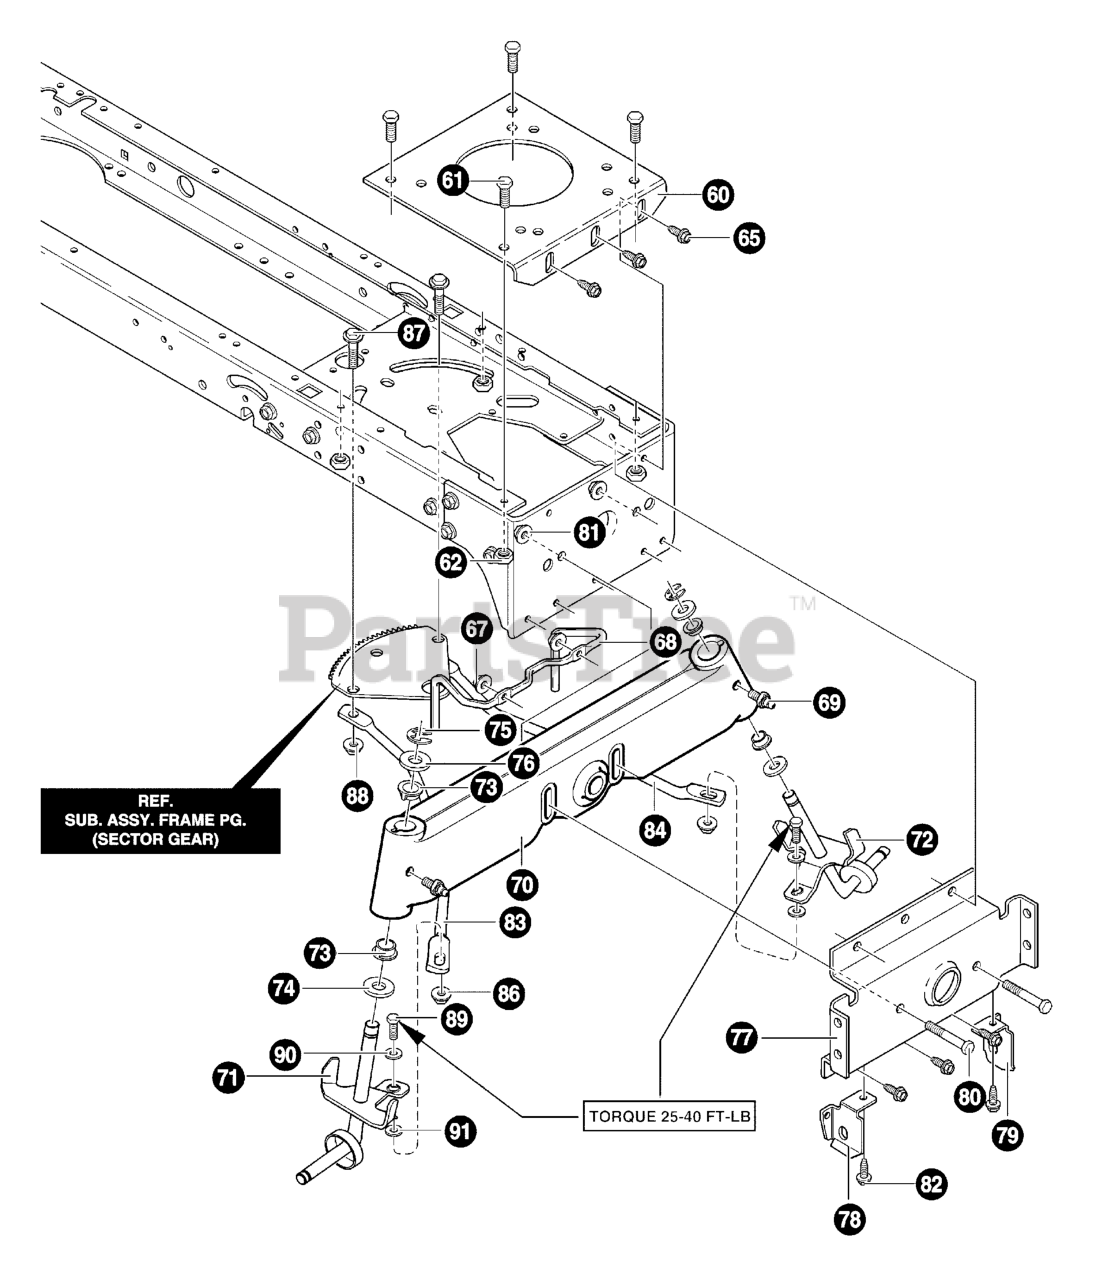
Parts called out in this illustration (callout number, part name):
60	PLATE, ENGINE
61	SCREW, 5/16-18 x 0.75
62	NUT, 5/16-18
65	SCREW, 5/16-18 x 0.75
67	NUT, 5/16-18 HEX
68	GUIDE-STACK PULLEY BELT
69	ZERK, GREASE FITTING
70	AXLE, CAST MACHINED
71	SPINDLE, LONG RH
72	SPINDLE, LONG LH
73	BEARING, SPINDLE
76	WASHER, FLAT
77	HANGER, AXLE
78	HANGER, DECK RH
79	HANGER, DECK LH
80	SCREW 5/16-18X3.00
81	NUT, 5/16-18
82	SCREW, 5/16-18 x 0.75
83	DRAG LINK LH
84	DRAG LINK RH
86	NUT, 3/8-16
87	BOLT, HHSH
88	NUT, 3/8-16
89	SCREW, 3/8-16 x 1.50
90	WASHER, FLAT
91	WASHER, FLAT
